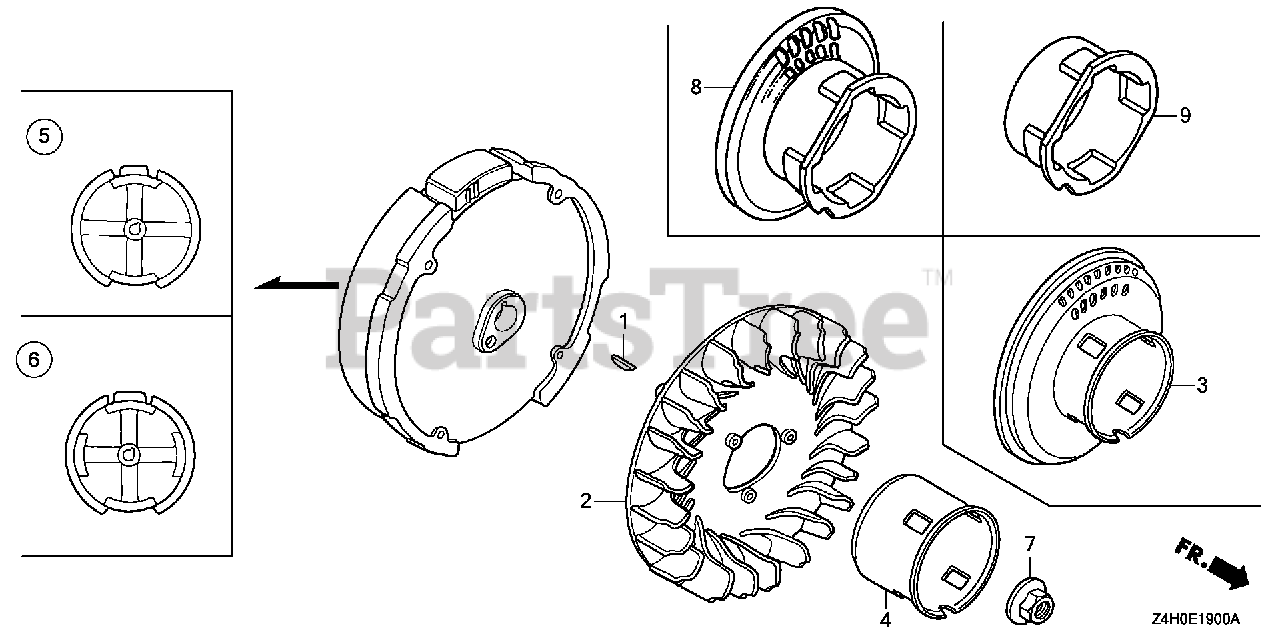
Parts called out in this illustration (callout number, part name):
1	KEY, SPECIAL WOODRUFF (25X18)
2	FAN, COOLING
3	PULLEY, STARTER
7	NUT, SPECIAL (14MM)
